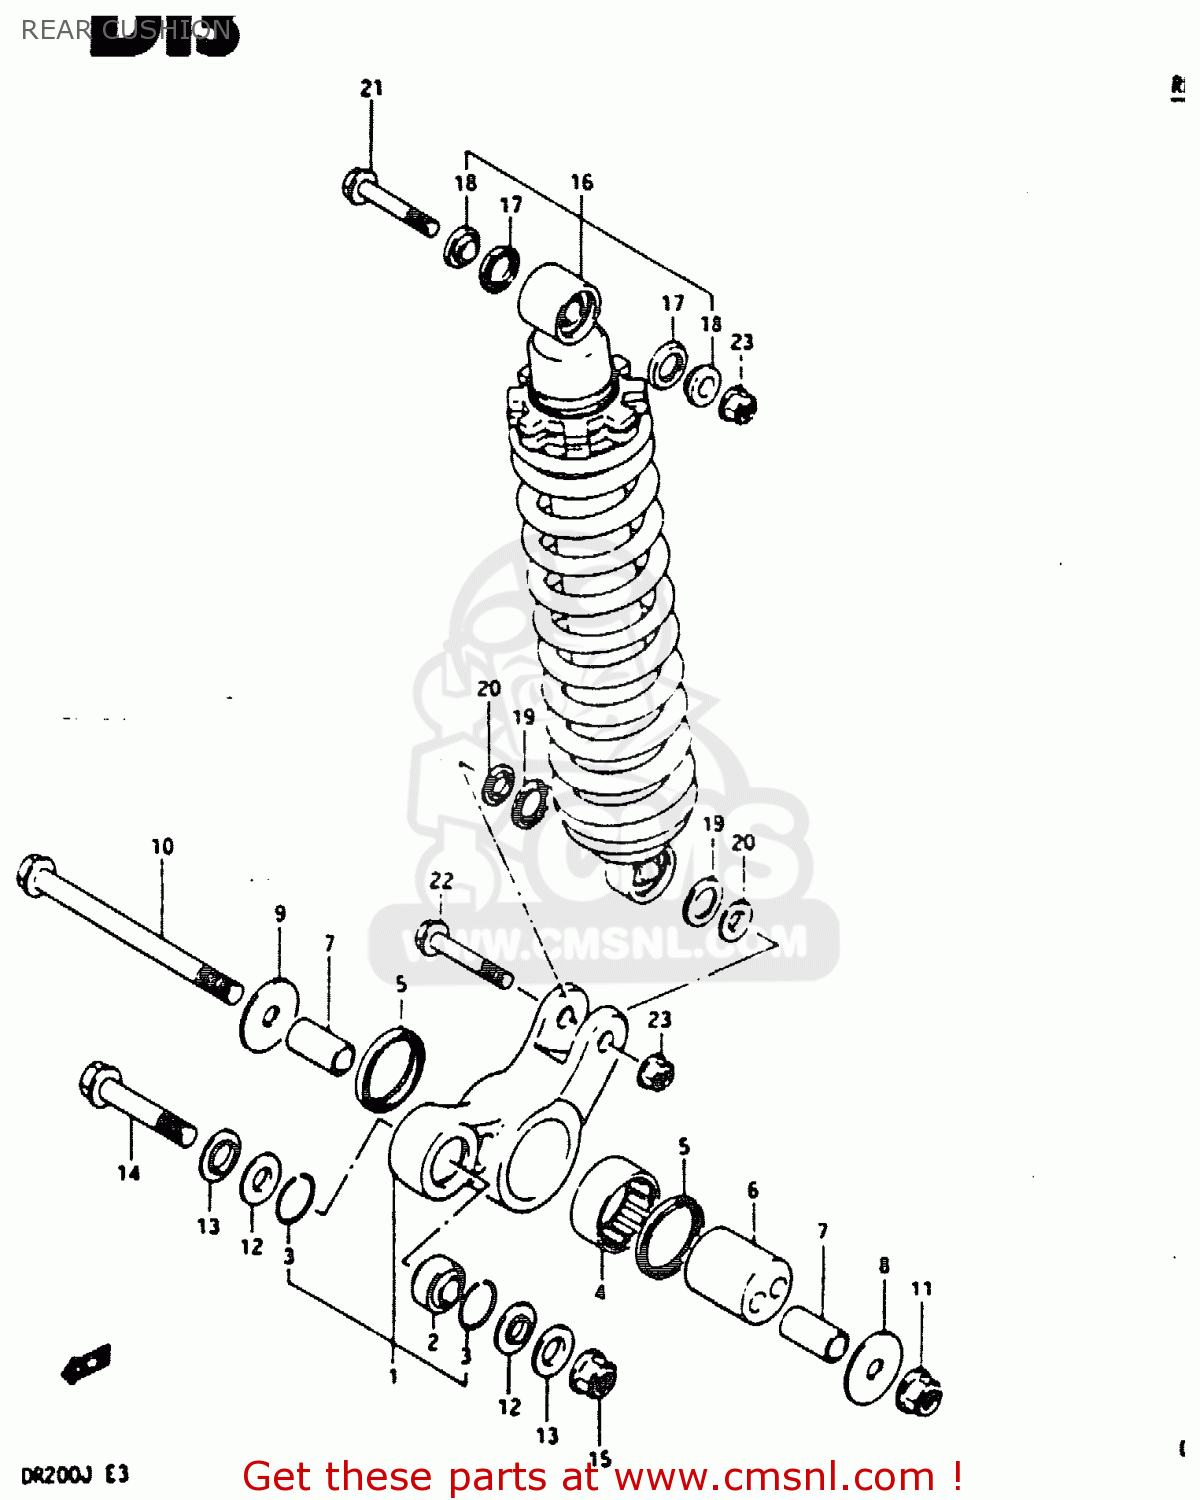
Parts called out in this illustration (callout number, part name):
1	LEVER SET,RR CUSHION
2	BEARING(12X26X16)
3	RING,STOPPER
4	BEARING(37X47X20)
5	SEAL,DUST
6	SPACER,RR SUSPENSION ECCENTRIC
7	SPACER,CUSHION LEVER SHAFT
8	WASHER(12X40X3)
9	WASHER,THRUST,R
10	SHAFT,REAR CUSHION LEVER
11	NUT 12MM
12	SEAL,RR CUSHION ROD DUST
13	SPACER,RR CUSHION ROD
14	BOLT,CUSHION LEVER FR
15	NUT 12MM
16	ABSORBER ASSEMBLY,REAR SHOCK
17	DUST SEAL
18	SPACER
19	SEAL,DUST
20	COLLAR
21	BOLT,REAR SHOCK ABSORBER
22	BOLT(10X48)
23	NUT
